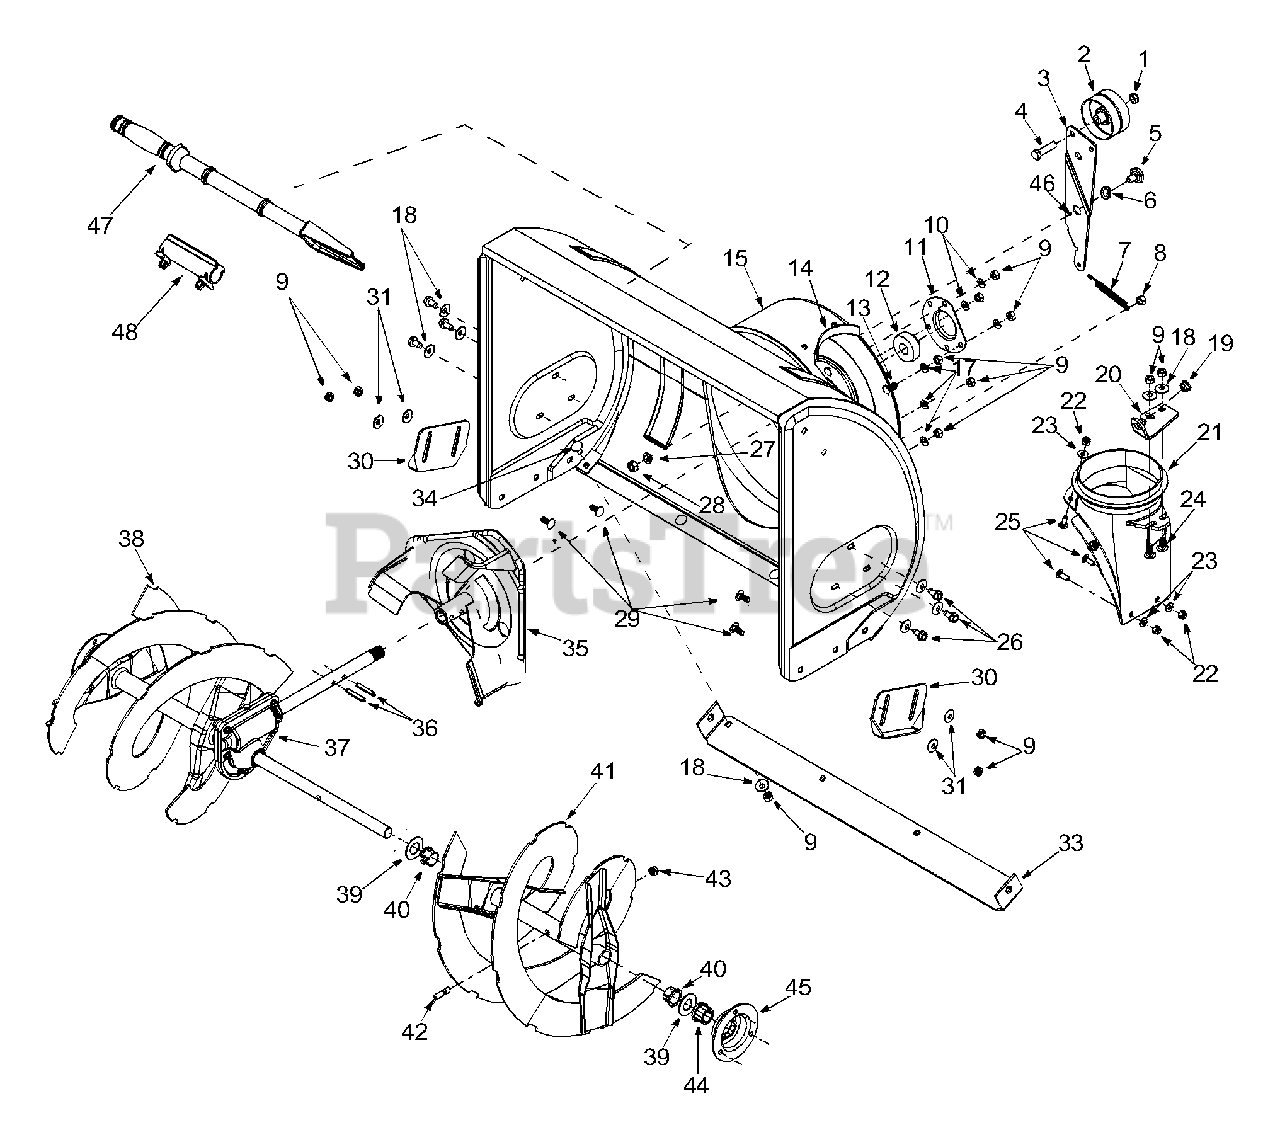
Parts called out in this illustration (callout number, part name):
1	Lock Jam Nut 3/8-24
2	Flat Idler
4	Hex Cap Screw 3/8-24 x 1.50
5	Shoulder Screw
6	Flat Washer
7	Extension Spring
8	Hex Nut 5/16-18
9	Hex Nut 5/16-18
10	Lock Washer 5/16
11	Housing
12	Ball Bearing
13	Carriage Bolt 5/16-18
18	Bell Washer
19	Bushing
21	Chute Adapter
22	Hex Lock Nut 1/4-20
23	Flat Washer
24	Carriage Bolt
25	Carriage Screw 1/4-20 x .75
26	Hex Washer Screw 5/16-18
27	Lock Washer 3/8
28	Hex Nut 3/8-16
29	Carriage Bolt 5/16-18 x .75
31	Bell Washer
34	Carriage Bolt 5/16-18 x .62
37	22" Gear Assembly
40	Flange Bushing
42	Shear Bolt 5/16-18 x 1.5
43	Lock Nut 5/16-18
44	Hex Flange Bearing
46	Grease
47	Chute Clean-out Tool
48	Mount, Chute Clean-out Tool
